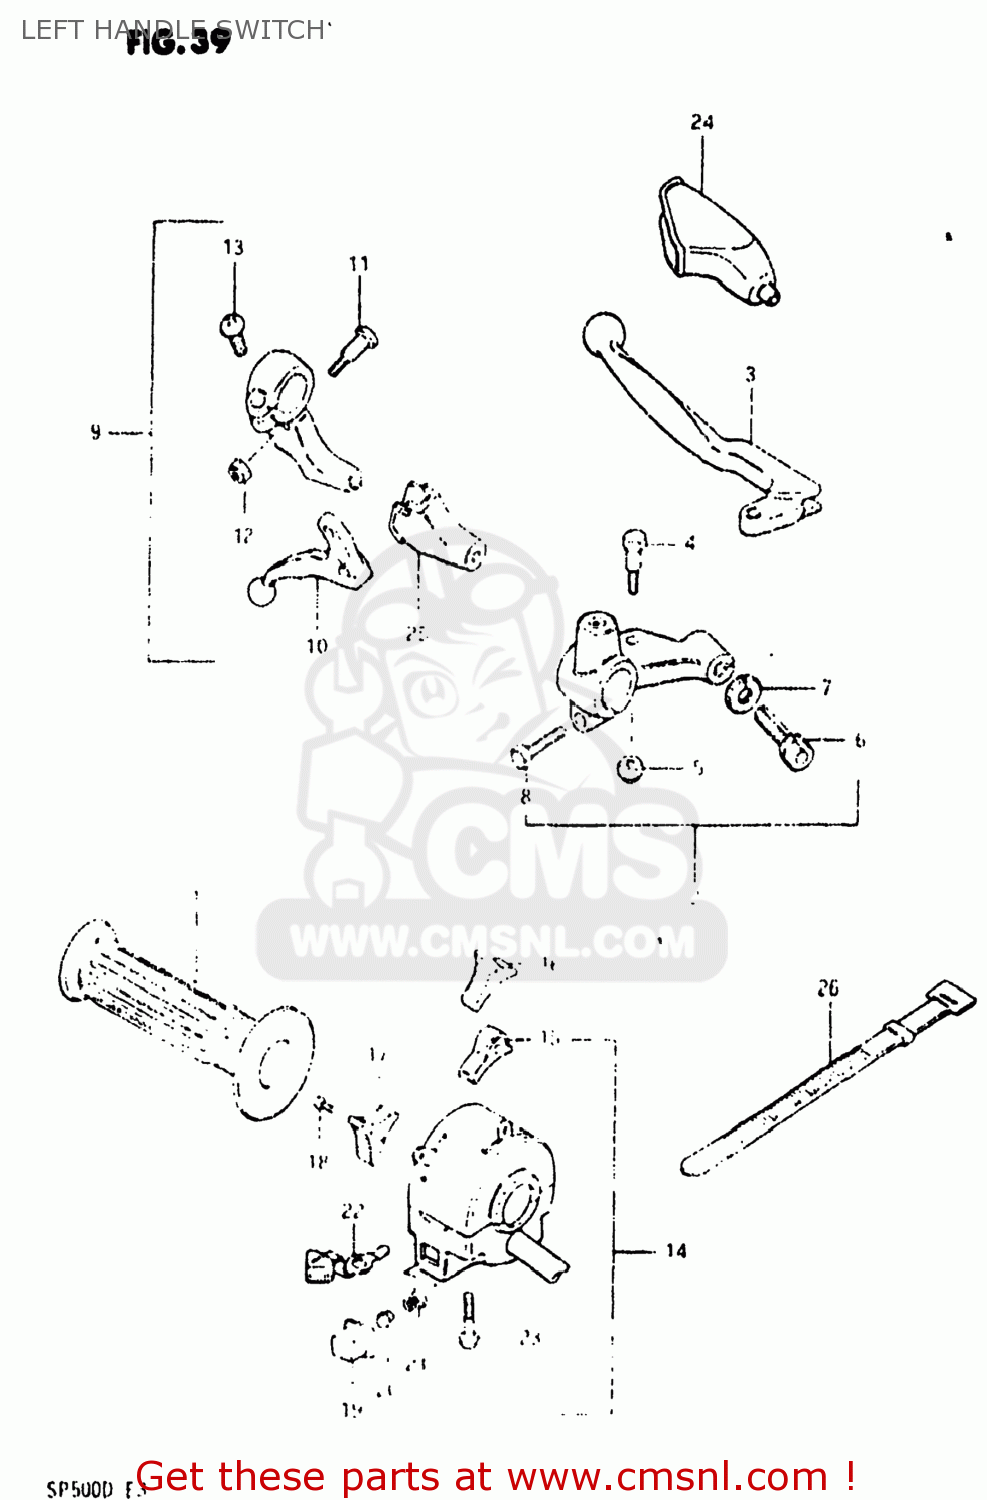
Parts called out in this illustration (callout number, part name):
1	GRIP,L
2	LEVER ASSY,CLUTCH
3	LEVER,CLUTCH
4	BOLT,LEVER
5	NUT 6MM
6	ADJUSTER,CABLE
7	NUT,CABLE ADJUSTER
8	BOLT,CLUTCH LEVER HOLDER
9	LEVER ASSEMBLY,DECOMPRESSION
10	LEVER,DECOMP
11	BOLT,LEVER
12	NUT
13	SCREW
14	SWITCH ASSEMBLY,HANDLE,LEFT
15	KNOB,STOP
16	KNOB,LIGHTING SWITCH
17	KNOB,DIMMER SWITCH
18	SCREW
19	BUTTON,HORN
20	CONTACT
21	SPRING
22	KNOB,TURNSIGNAL
23	SCREW
24	COVER,CLUTCH LEVER
25	COVER,DECOMP LEVER DUST
26	CLAMP
